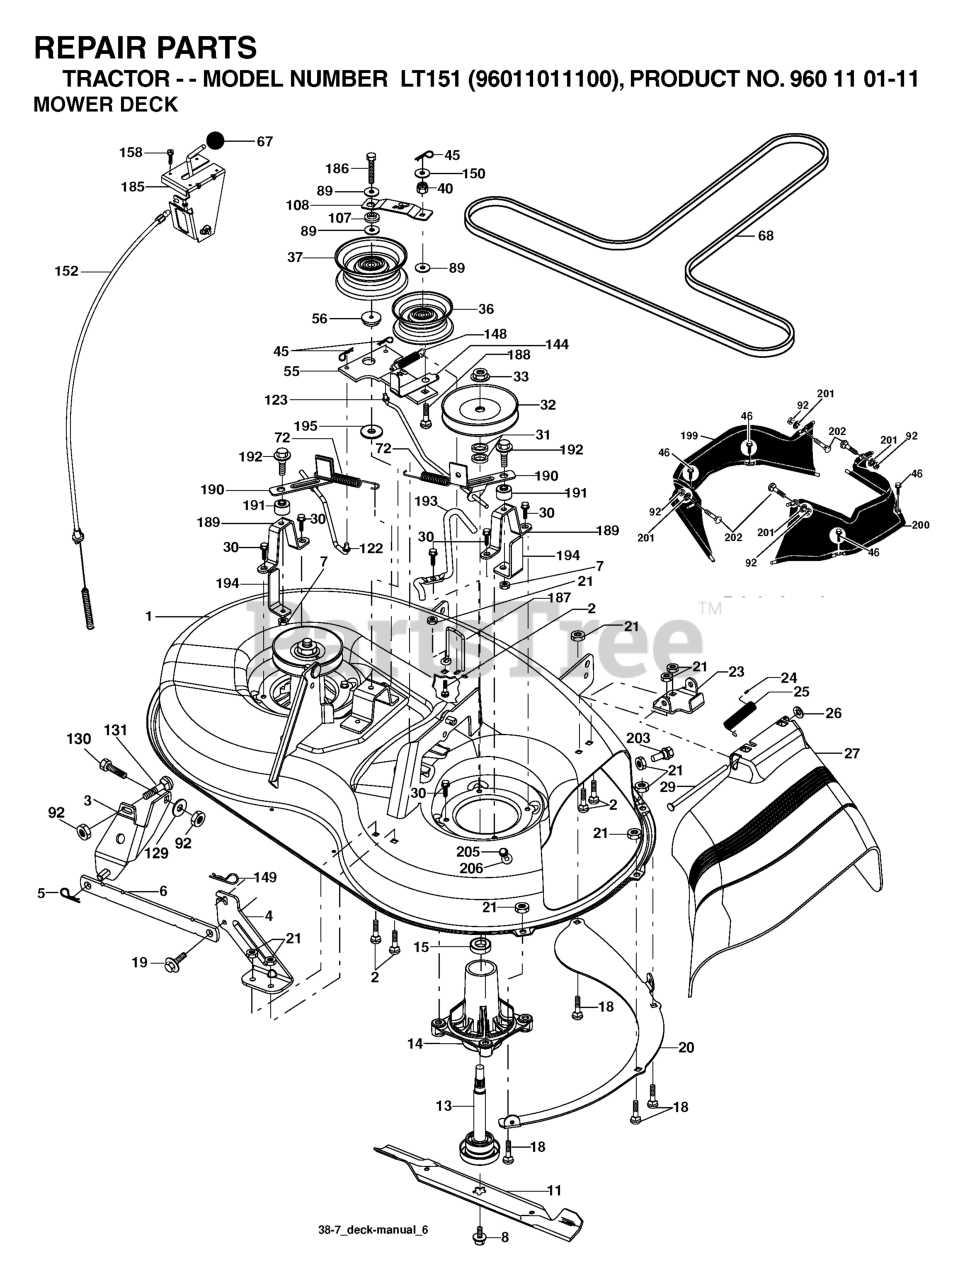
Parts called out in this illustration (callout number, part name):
1	DECK SVCX1 38/94 192556X431
2	RP BOLT 5/16-18 X3/4 ZN/YEL GR
3	BRKT ASM SWAY BAR
4	BRACKET DECK SWAY BAR 38"/42"
5	RETAINER-SPRNG RB
6	BAR SWAY DECK
7	NUT.71038.31-18.HEX.NYLOCK
8	BOLT.WASHER.ASM.7/16-2
11	BLADE 38" PREMIUM
13	SHAFT.ASM.MDRL.N/GREASE.38
14	RP.HOUSING.MANDREL.4PT.
18	BOLT
19	BOLT SHD 5/16-18
20	BAFFLE.VORTEX.FRONT.38"
21	LOCKNUT
23	BRKT.DEFLECTOR.38"2005+
24	CAP-SLEEVE LT
25	SPRING.TORSION.DEFLECT
26	NUT PUSH M
27	SHIELD ASM.DFLCTR MWR.38-7"BLK
29	ROD.HINGE
30	SCREW, WASHER HEAD
31	WASHER.SPACER.MANDREL
32	PULLEY MANDREL
33	NUT.FLANGE.LOCK.TOP
36	FLAT IDLER PULLEY
37	PULLEY.IDLER.FLAT.UNPLATED
45	RETAINER M
46	SCREW.1/4-20X5/8
56	SPACER.RETAINER.MOWER
67	KNOB T (3/8 HOLE)
68	V-BELT.MOWER.38"2005+
72	SPRING.BRAKE.RETURN.38"
89	WASHER
92	NUT
107	SPACER.IDLER.ARM
108	STIFFENER.IDLER.ARM
122	LINKAGE.BRAKE.LH.38"
123	LINKAGE.BRAKE.RH.38"
129	WASHER
131	BOLT D
144	KEEPER BELT
148	IDLER RETURN SPRING
149	SPRING.RETAINER.YELLOW.ZINC
152	CABLE.CLUTCH.38".SERVICE
158	SCREW
185	HEAD ASM. CABLE CLUTCH
186	SCREW.HXWSH.3/8
187	KEEPER BELT
188	BOLT, CARRIAGE IDLER
189	STAND, BRAKE
190	ARM, BRAKE
191	BRAKE.SPACER.38".DECK
192	BOLT/WASHER ASM 5/16-18
193	KEEPER BELT RH MANDREL
194	GUARD BRAKE
195	WASHER 12/32X2X10GA
201	PUSH.NUT.ROUND.3/8.DIAM
202	BOLT D
205	SCREW
